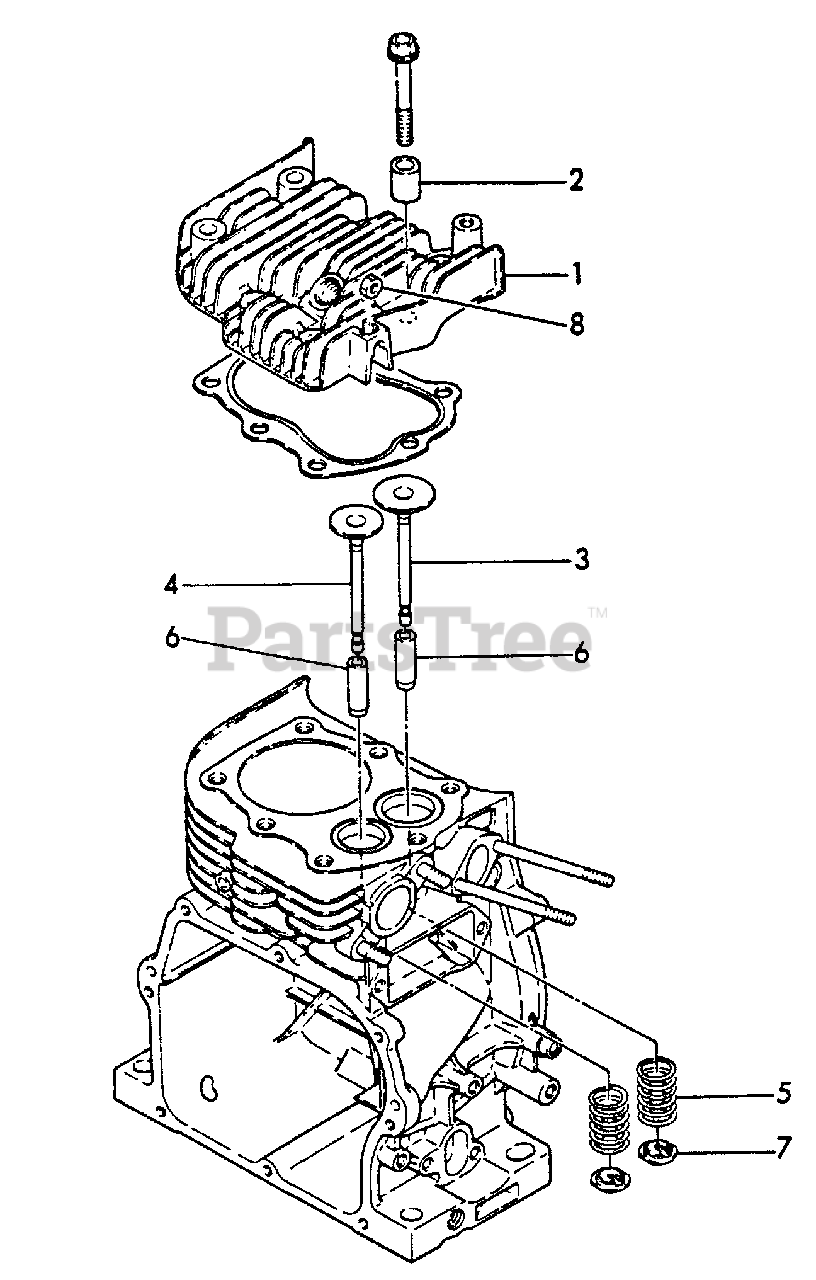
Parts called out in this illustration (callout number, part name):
1	HEAD, CYLINDER
2	SPACER
3	VALVE, INTAKE
4	VALVE, EXHAUST
5	SPRING, VALVE
6	GUIDE, VALVE
7	RETAINER, SPRING
8	LOCKNUT - 6 -- PLATED
